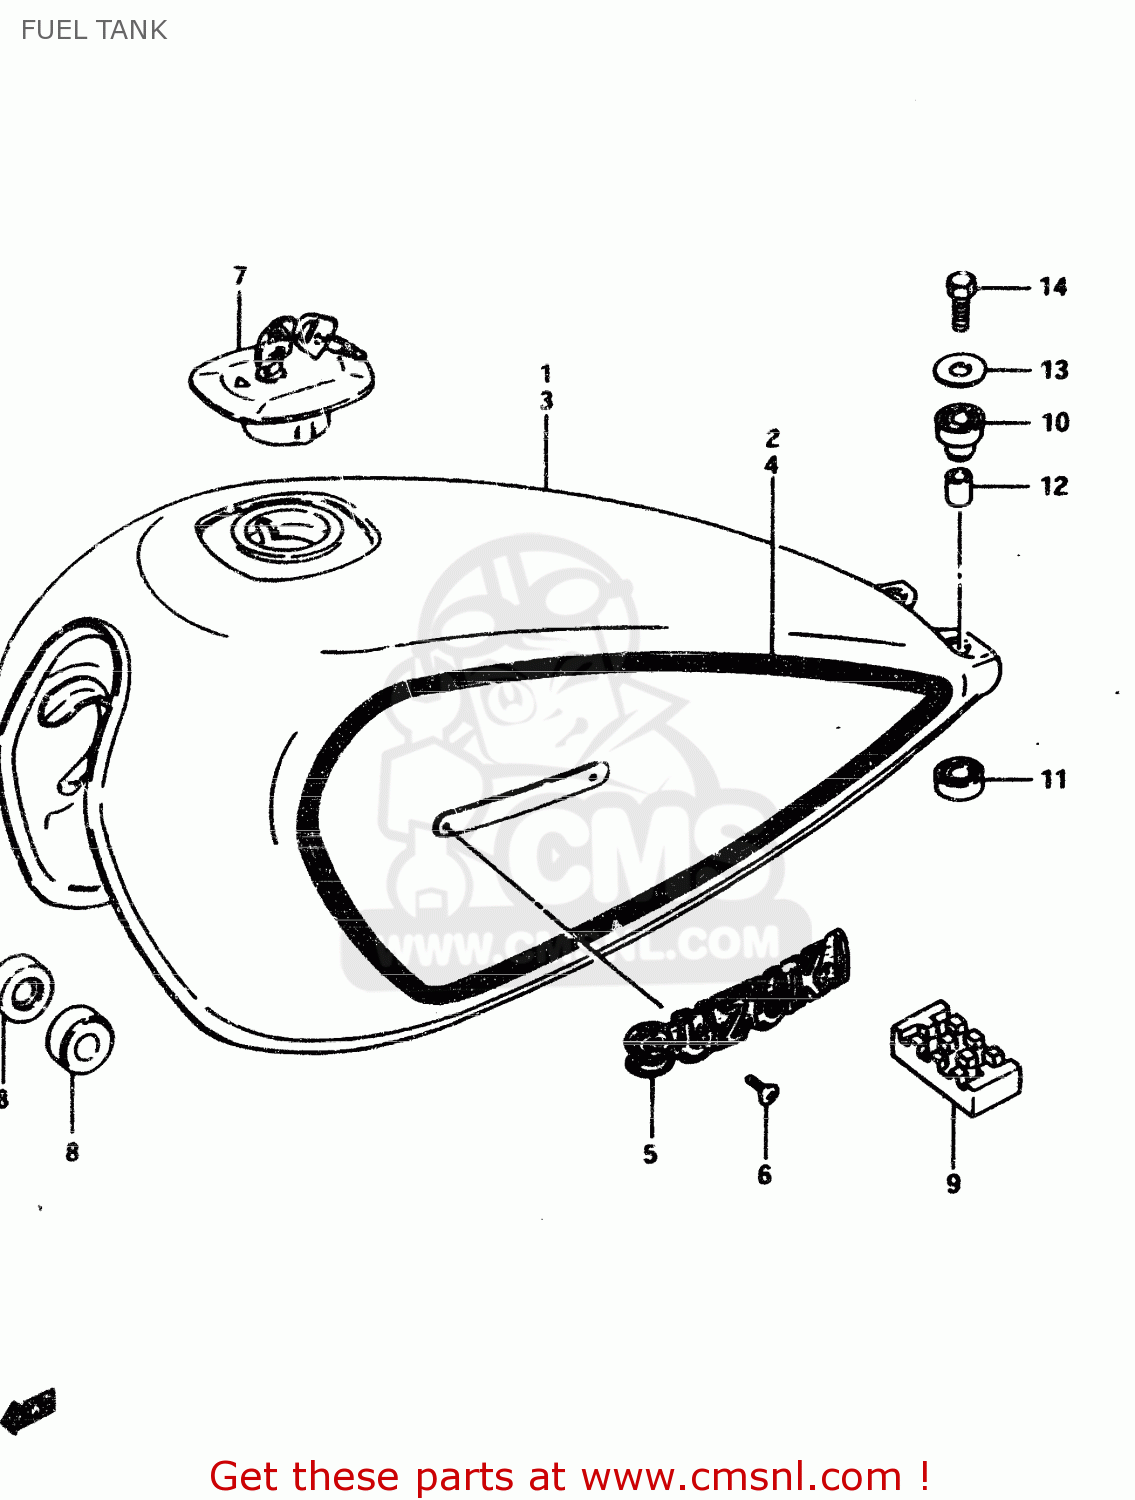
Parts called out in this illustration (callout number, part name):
1	TANK ASSEMBLY,FUEL
2	TAPE SET,FUEL TANK
3	TANK ASSEMBLY,FUEL
4	TAPE SET,FUEL TANK
5	EMBLEM,FUEL TANK
6	SCREW 3X6
7	CAP SET,FUEL TANK
8	CUSHION
9	CUSHION
10	CUSHION
11	CUSHION
12	SPACER (6.4X9X20)
13	WASHER (6.5X24X1.6)
14	BOLT
